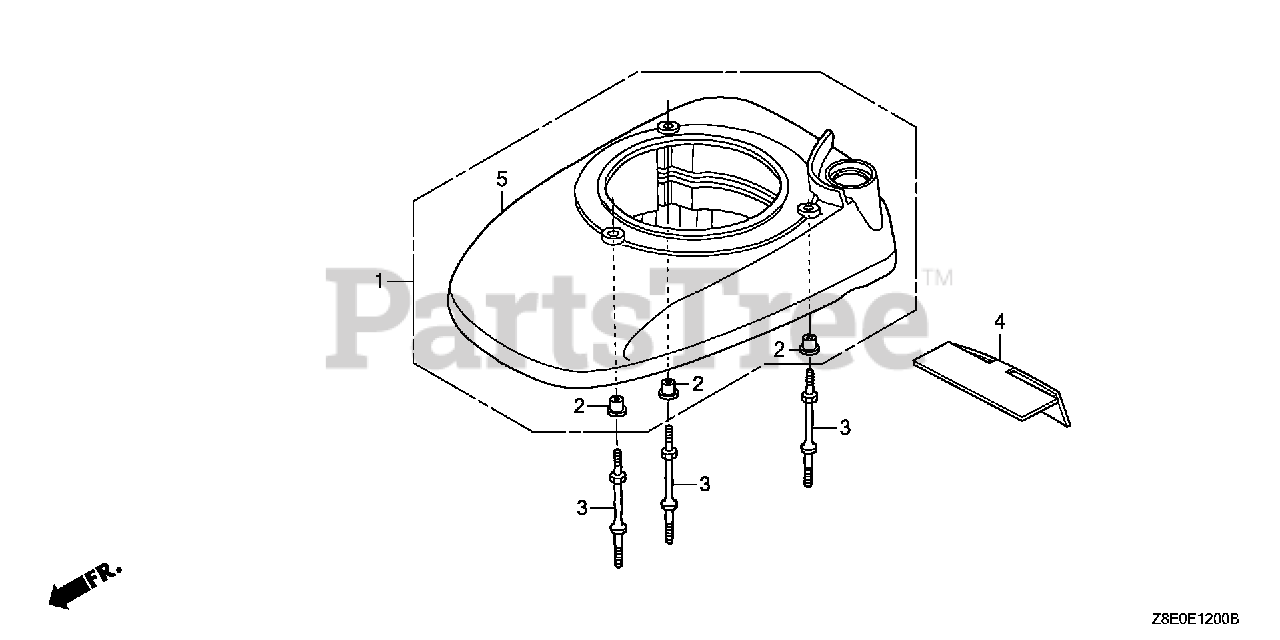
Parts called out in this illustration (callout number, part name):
1	COVER, FAN *R280* (POWER RED)
2	COLLAR, FAN COVER
3	BOLT, STUD (H=42.5MM)
3	BOLT, STUD (FAN COVER)
4	RUBBER, FAN COVER
5	COVER, FAN *R280* (POWER RED)
